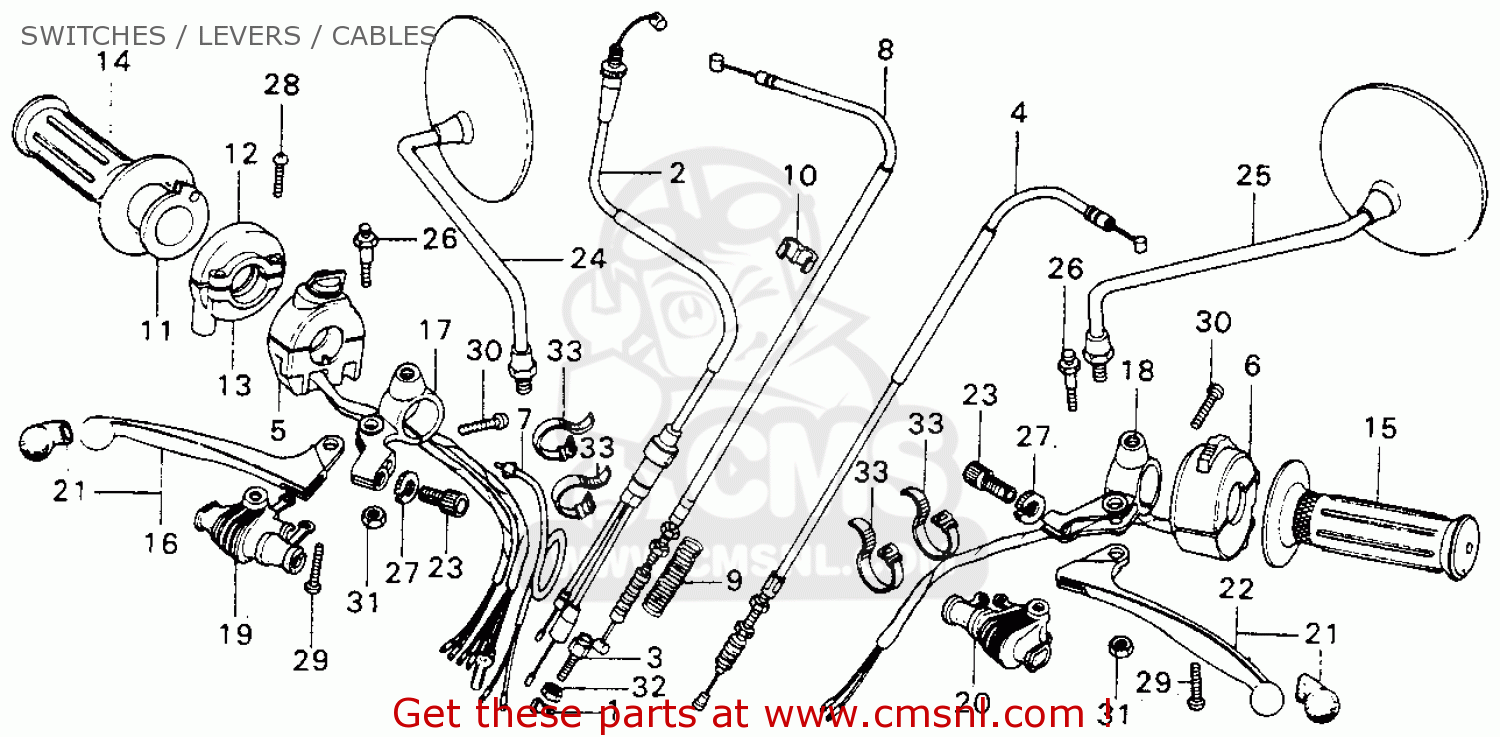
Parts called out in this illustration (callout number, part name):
1	PIN, CONTROL LEVER
2	CABLE, THROTTLE
3	BOLT, THROTTLE CABLE
4	CABLE.,CLUTCH
5	SWITCH,LIGHTING
6	SWITCH, DIMMER
7	SWITCH,FR.STOP
8	CABLE,FR.BRAKE
9	SPRING,FR. BRAKE
10	CLIP, BRAKE WIRE
11	PIPE.THROT.GRIP
12	CASE,UPPER
13	CASE,UNDER
14	GRIP,R-HANDLE
15	GRIP,L-HANDLE
16	LEVER,R
17	BRACKET,R.LEVER
18	BRACKET,L.LEVER
19	COVER,R-STRG.LEV.
20	COVER,L.STRG.LEV.
21	CAP LEVER
22	LEVER,L
23	BOLT
24	MIRROR,R BACK
25	MIRROR L BACK
26	BOLT,HANDLE LEV.
27	NUT,FIXING
28	SCREW,PAN,5X20
29	SCREW,PAN,5X28
30	SCREW,PAN,6X28
31	NUT HEX 6MM
32	NUT,HEX.,8MM
33	BAND,B1 WIRE
